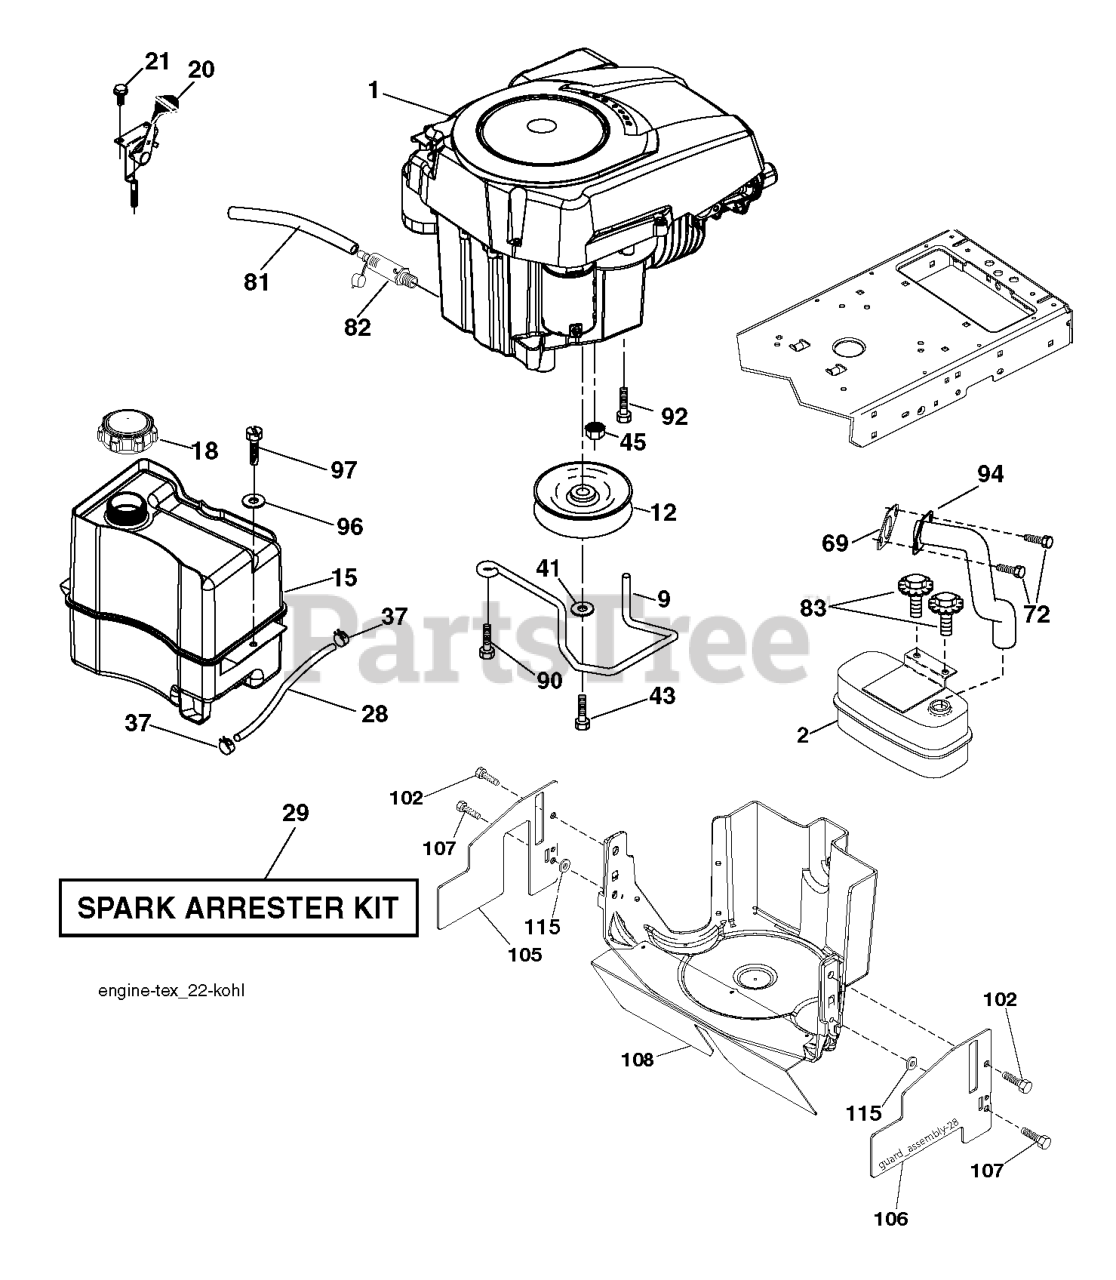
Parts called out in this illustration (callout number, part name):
2	MUFFLER.SINGLE.CYL.KOHL/B&S
9	KEEPER.BELT.ENGINE.3.25 (3 2)
12	PULLEY ENGINE
15	RP TANK FUEL FRT 1.5 GAL
18	FUEL CAP
20	CONTROL.TH/CK.C.
21	SCREW.#10 X 0.750.BOS
28	LINE.FUEL.20
29	KIT.SPARK ARRESTOR 794945 B&S
37	HOSE CLAMP
41	LOCKWASHER
43	BOLT HEX 7/16-20X4-1/4"
45	NUT
69	GASKET.EXHAUST.KOHLER
72	SCREW.SOCKET HD.5/16-1
81	TUBE, DRAIN OIL ASM.
82	PLUG DRAIN OIL EASY
83	BOLT.5/16-18UNCX3/4 W/SEMS.BLK
90	SCREW 3/8-16X1
92	SCREW 3/8-16X1
94	RP.TUBE.EXHAUST.KOHL.COURAGE
97	SCREW HEXWSHR 1/4-20X3/4
102	SCREW
105	SHIELD.SIDE.LH.3842"TEX FRENCH
106	SHIELD.SIDE.RH.3842"TEX FRENCH
107	SCREW.1/4-20X5/8
108	ENGINE COVER
115	PALNUT 1/4
